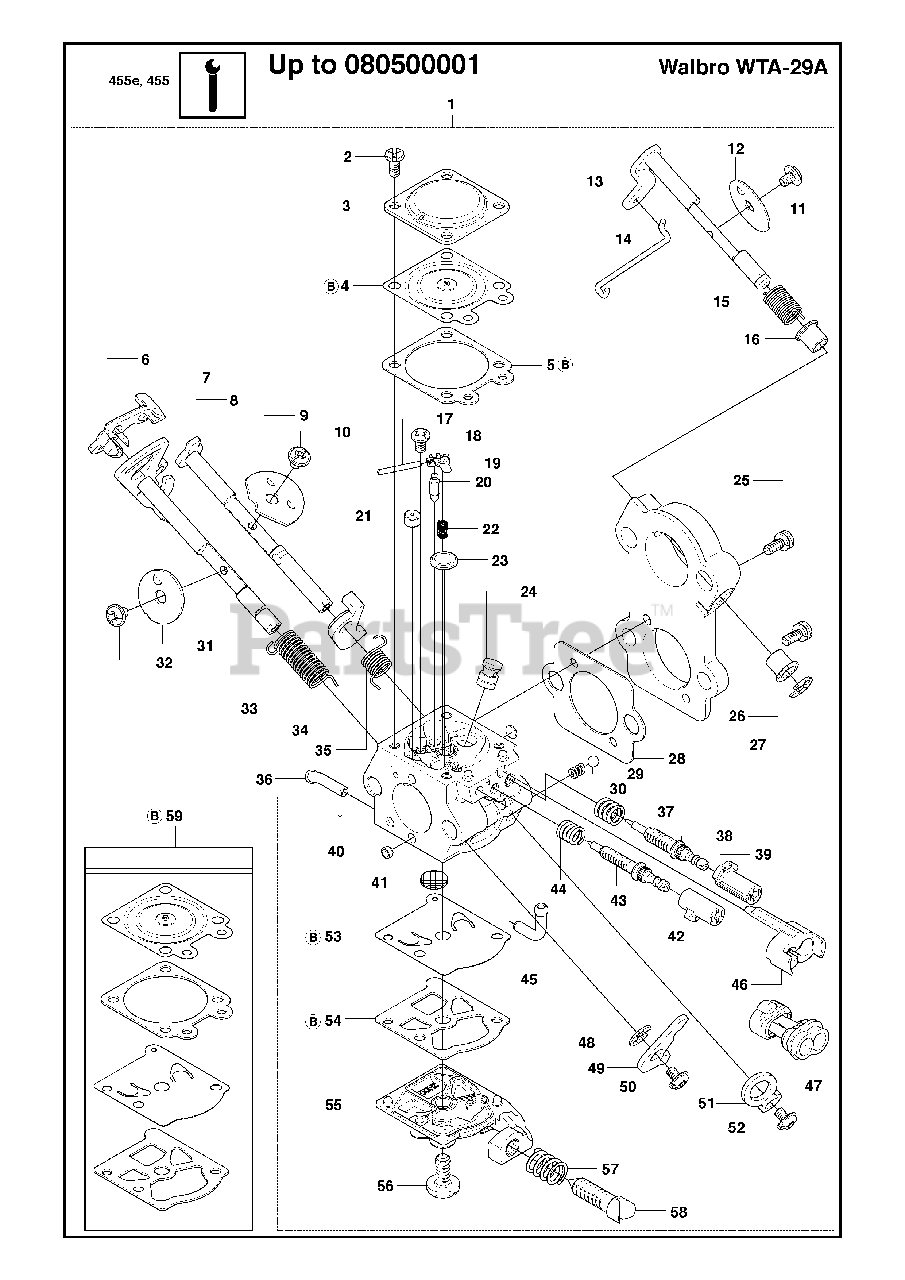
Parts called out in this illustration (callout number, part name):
1	CARBURETOR
3	DIAPHRAGM COVER
12	CHOKE FLAP
17	FULCRUM PIN
20	INLET NEEDLE
23	WELCH PLUG
31	THROTTLE FLAP
32	SCREW SHUTTERS
37	SPRING, H-NEEDLE
38	SCREW
39	LIMITER CAP
41	FUEL INLET SCREEN
42	LIMITER CAP
43	SCREW
44	SPRING/COMPRESSION
53	PUMP DIAPHRAGM
59	GASKET SET
